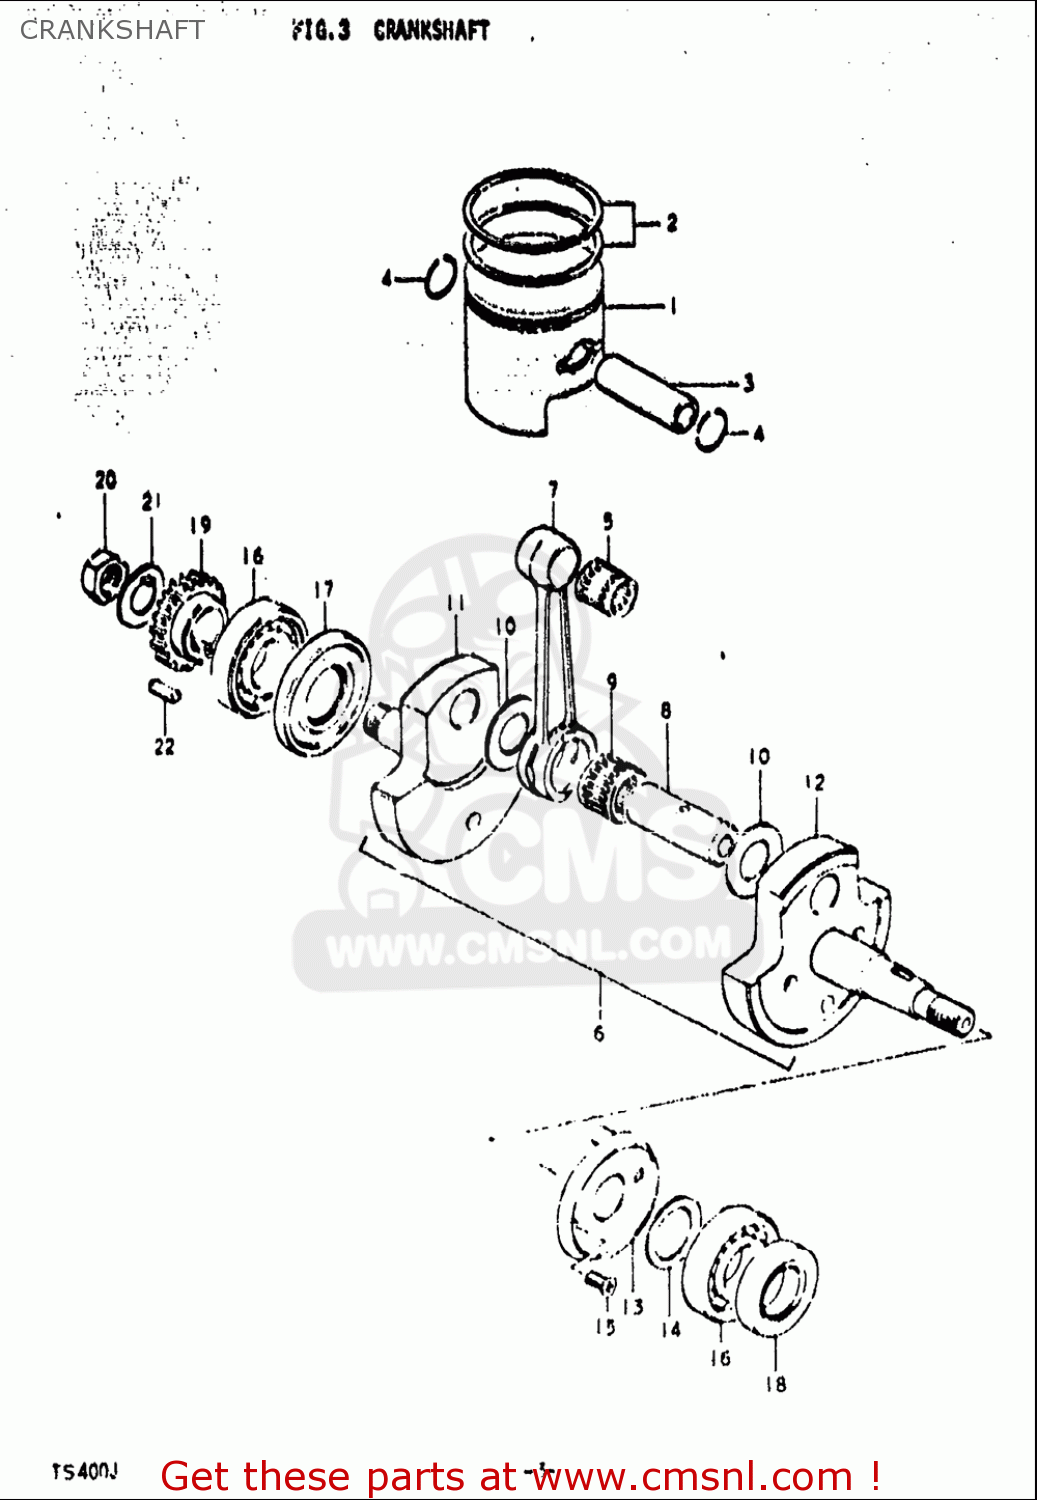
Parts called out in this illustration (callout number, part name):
1	PISTON (82.00MM)
3	PIN,PISTON
4	CIRCLIP,PISTON PIN
5	BEARING(20X25X27.9)
8	PIN,CRANK
9	BEARING
14	WASHER
15	SCREW
16	BEARING(30X72X19)
17	SEAL,OIL(40X72X9)
18	OIL SEAL (30X55X10)
20	NUT (20MM)
22	KEY
